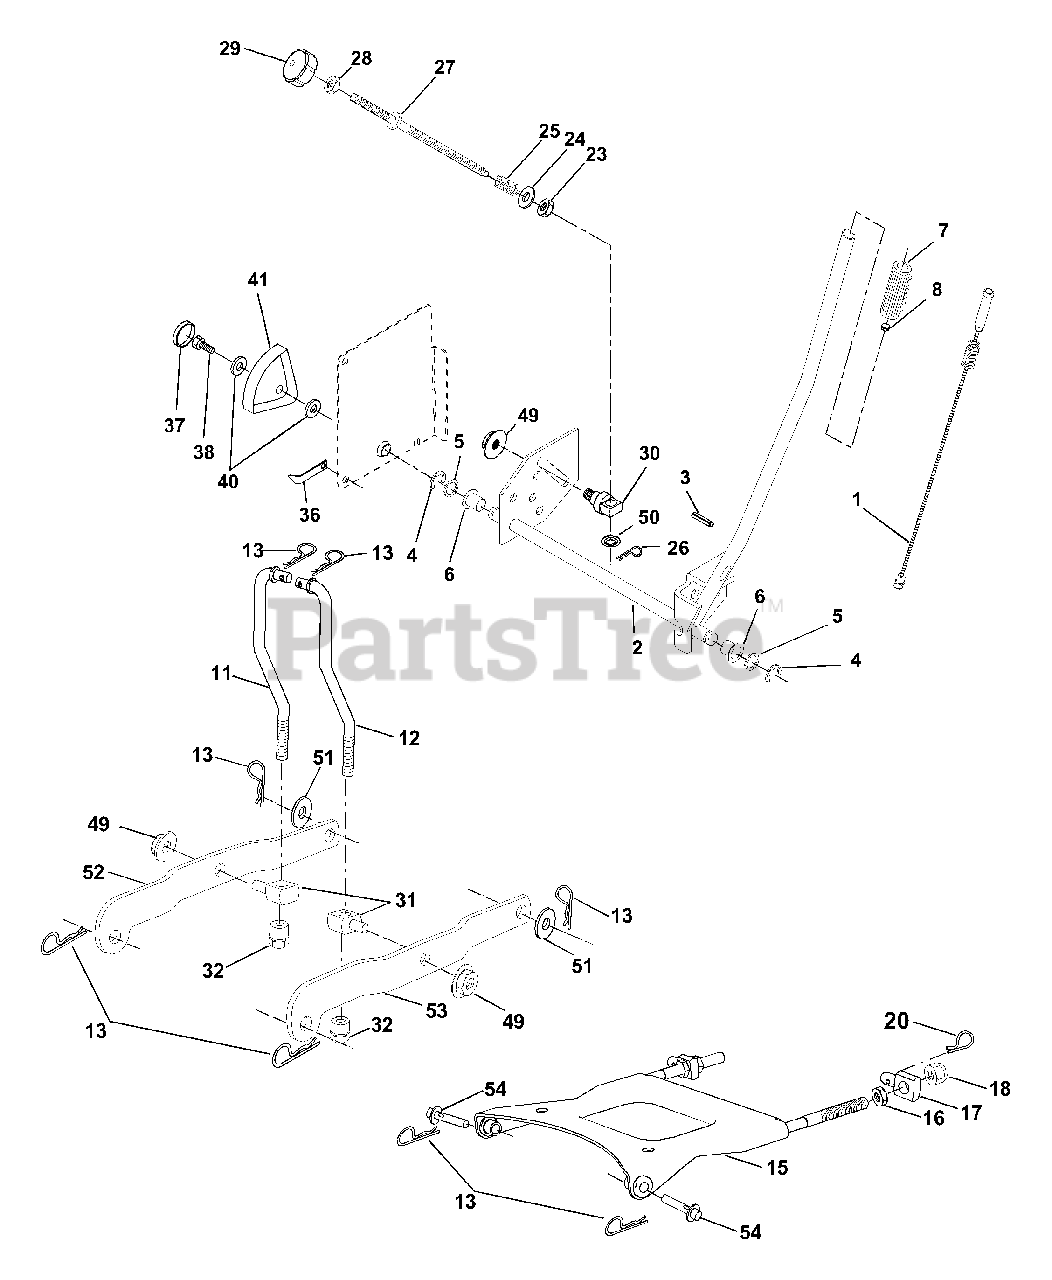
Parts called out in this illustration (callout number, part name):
1	Wire Asm Inner/Spring W/Plunger LT
2	Shaft Asm Lift RH w/Inf
3	Pin Groove 1 500 Zinc
4	E Ring #5133-62
5	Washer 21/32 X 1 X 21 Ga
6	Bearing Nylon Blk 629 Id
7	Grip Handle Fluted Blk
8	Button Plunger Black
11	Link Lift LH Fixed Length
12	Link Lift RH Fixed Length
13	Retainer Spring
15	Plate Asm. Susp. Front
16	Nut Jam Hex 1/2-13 Unc
17	Trunnion Blk Zinc
18	Nut Lock w/Wsh 1/2-13unc
20	Retainer Spring
23	Nut Special
24	Washer 13/32 X 5/8 X 16 Ga
25	Spring 2-1/8"
26	Retainer Clip
27	Rod Adj Lift Zinc 7.49 Wrk Lg
28	Nut Hex Jam 3/8-16 Unc
29	Knob Inf 3/8-16 Unc Blk W/sym
30	Trunnion Infin Height
31	Trunnion Susp. Arm
32	Nut Crownlock 3/8 - 24
36	Indicator Height STLT
37	Plug Hole Blk 1.485/1.515 Dia.
38	Screw 5/16-18 x 1
40	Washer 11/32 x 1-1/2 10 Ga.
41	Scale Ind. Height Blk.
49	Nut Hex Flange Lock
50	Nut, Push Phos & Oil
51	Washer 17/32 x 7/8 x 16
52	Arm Susp. Rear LH
53	Arm Susp. Rear RH
54	Pin Flange
